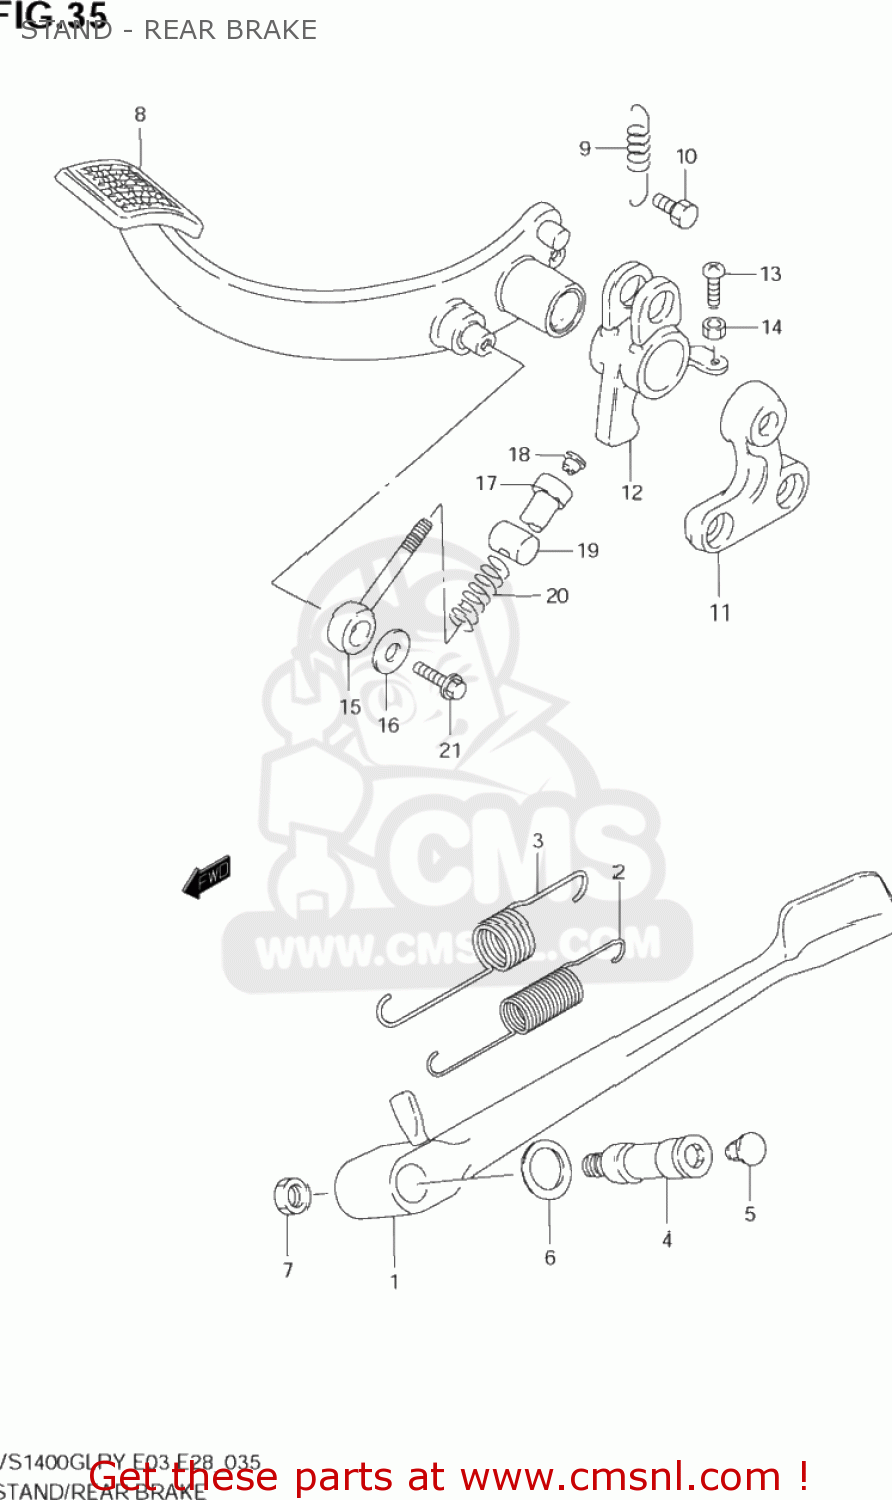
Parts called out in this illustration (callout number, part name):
1	STAND,PROP
2	SPRING
3	SPRING
4	BOLT,PROP STAND
5	CAP(OD:12)
6	THRUST WASHER
7	NUT
8	PEDAL ASSY,BRAKE
9	SPRING
10	SCREW(6X10)
11	BRACKET,BRAKE PEDAL BOSS
12	ARM,RR BRAKE
13	SCREW(5X14)
14	NUT
15	LINK,BRAKE PEDAL
16	WASHER(6.5X18X1.5)
17	NUT,BRAKE PEDAL LINK
18	CAP(OD:10)
19	PIN
20	SPRING
21	BOLT
